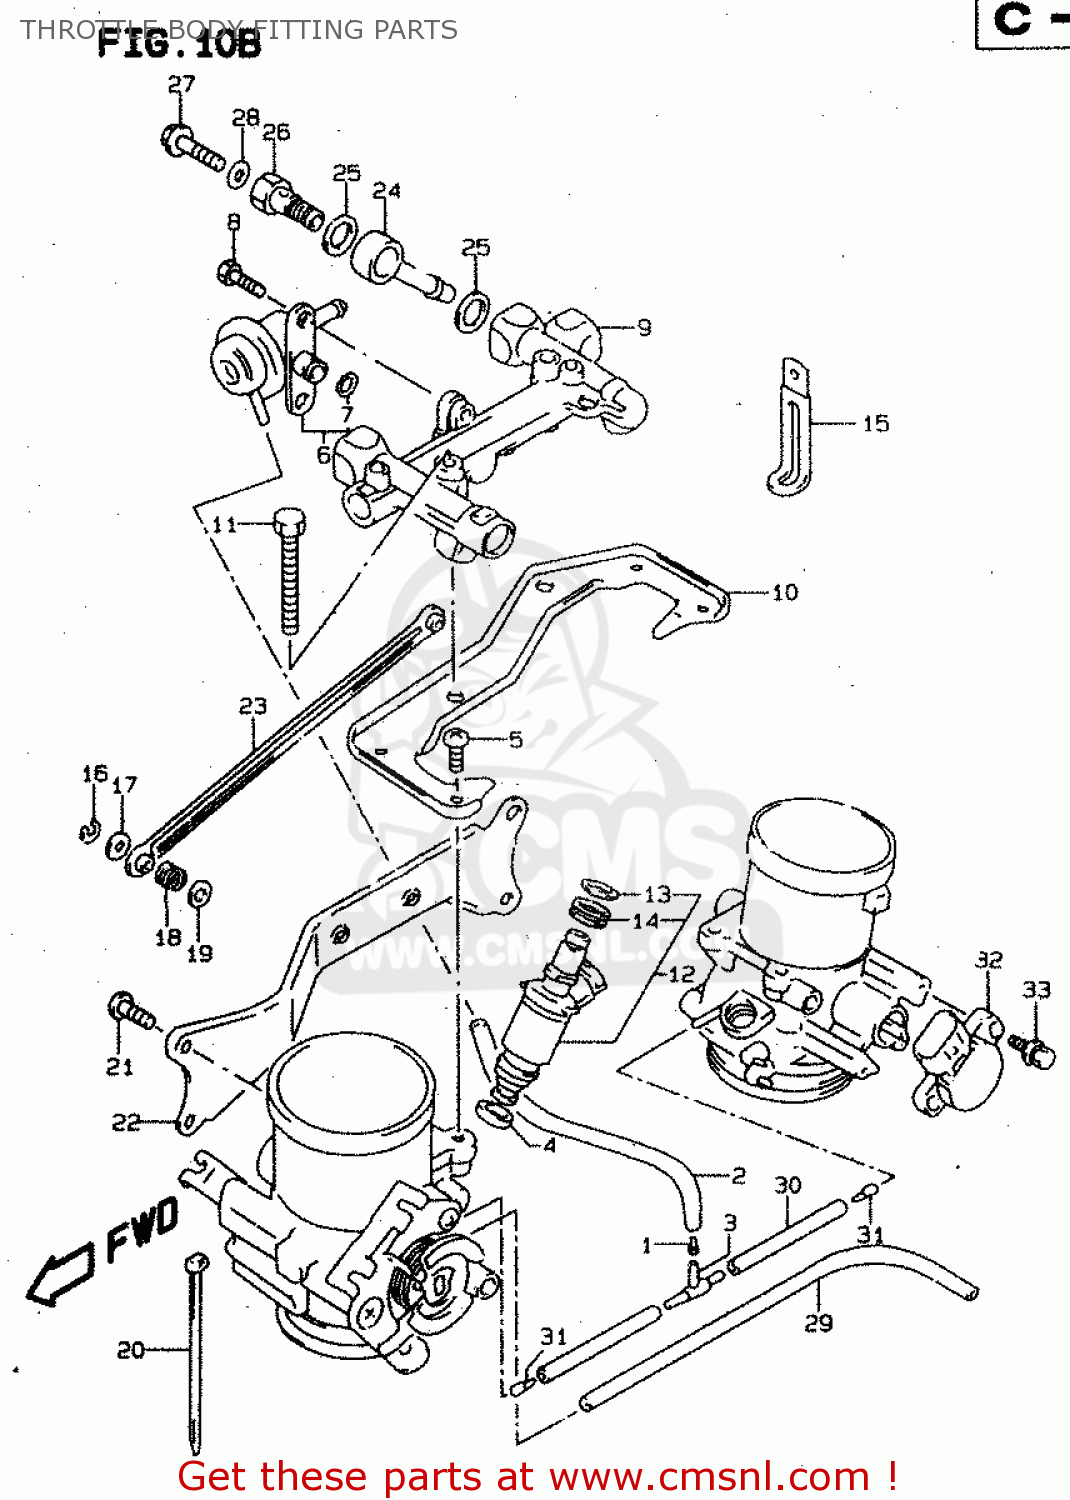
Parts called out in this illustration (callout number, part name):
1	JET
2	HOSE
3	3 WAY
4	CUSHION
5	SCREW
6	REGULATOR COMP,FUEL
7	O RING
8	BOLT
9	PIPE ASSY,DELIVERY
10	PLATE
11	BOLT
12	INJECTOR ASSY,FUEL
13	O RING
14	GROMMET
15	CLAMP(L:65)
16	E RING,ACCELETION LEVER
17	RING
18	SPRING
19	RING
20	CLIP
21	SCREW
22	PLATE
23	LEVER ASSEMBLY
24	UNION,FUEL HOSE
25	GASKET,UNION BOLT (NAS)
26	BOLT,UNION FUEL FILTER
27	UNION BOLT,AIR VENT
28	GASKET(5.8X13X1.2) (NAS)
29	HOSE
30	HOSE
31	JET
32	SENSOR ASSY,THROTTLE
33	SCREW
